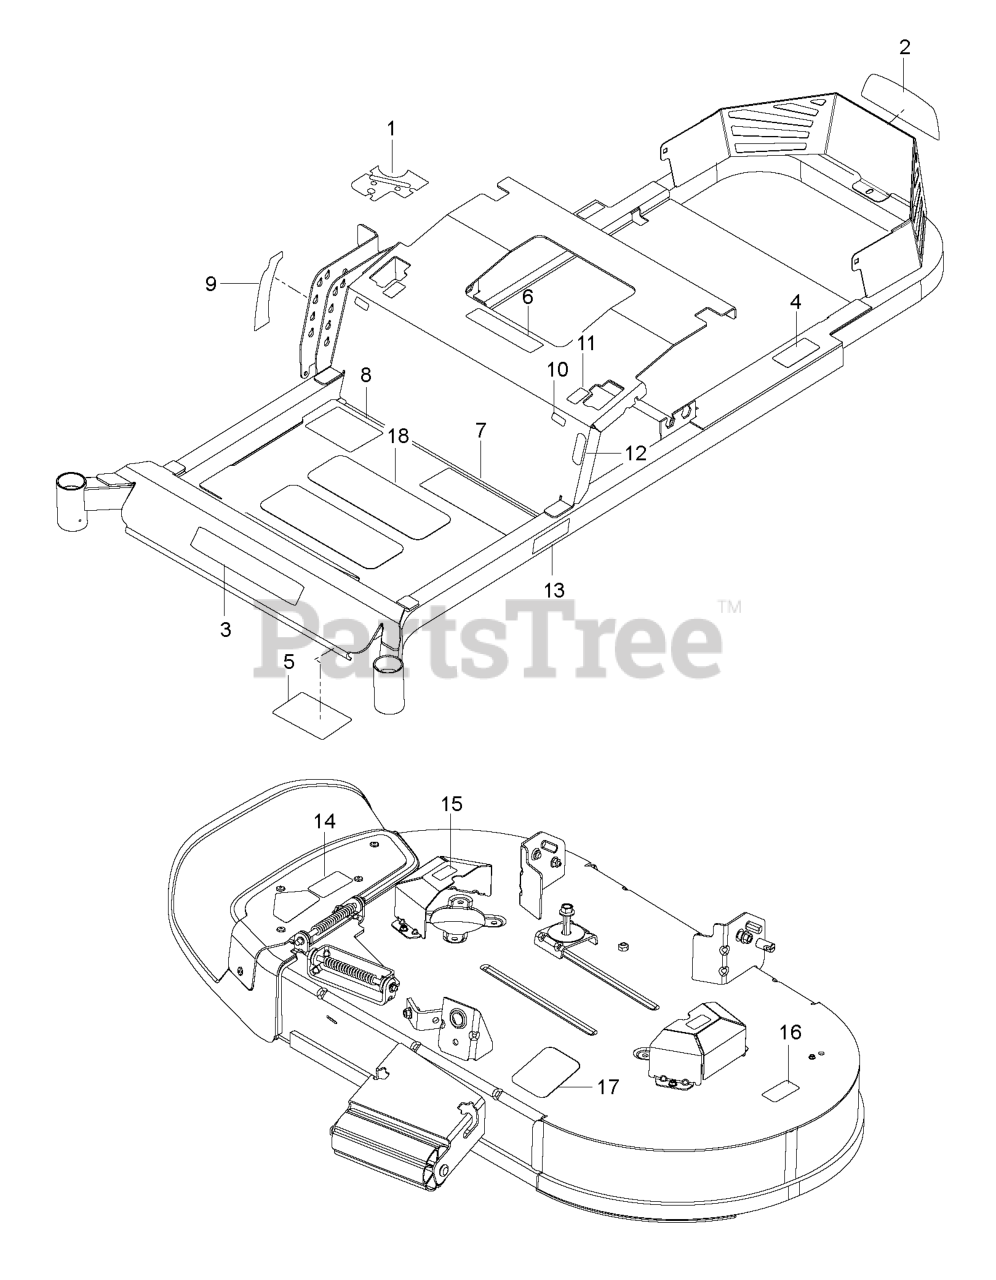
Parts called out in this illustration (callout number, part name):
1	DECAL CTRL PANEL GRAPHIC DECAL
2	DECAL ZTR BRAND GRAPHIC DECAL.
3	DECAL ZTR BRAND GRAPHIC DECAL.
4	DECAL, DO NOT TOW
5	DECAL, SERVICE
6	EURO DECAL-BATTERY WARNIN6
7	DECAL ZTR WARNING DECAL DECAL.
8	DECAL ZTR STARTING DECAL
9	DECAL.ZTR.HTADJ.LTRD.RZ2015PPR
10	DECAL.ZTR.TRACKING.GRAPHIC
11	DECAL.ZTR.MTNCONTROL.2015.PPRO
12	DECAL.ZTR.TRACKING.GRAPHIC
13	DECAL ZTR SIDE RAIL GRAPHIC DE
14	DECAL DECK WARNING GRAPHIC DEC
15	DECAL.DECK.CLEARCUT.NOSTEP
16	DECAL DECK DECAL DECAL.DECK.42
17	DECAL, BELT ROUTING
18	ANTI-SKID PAD
